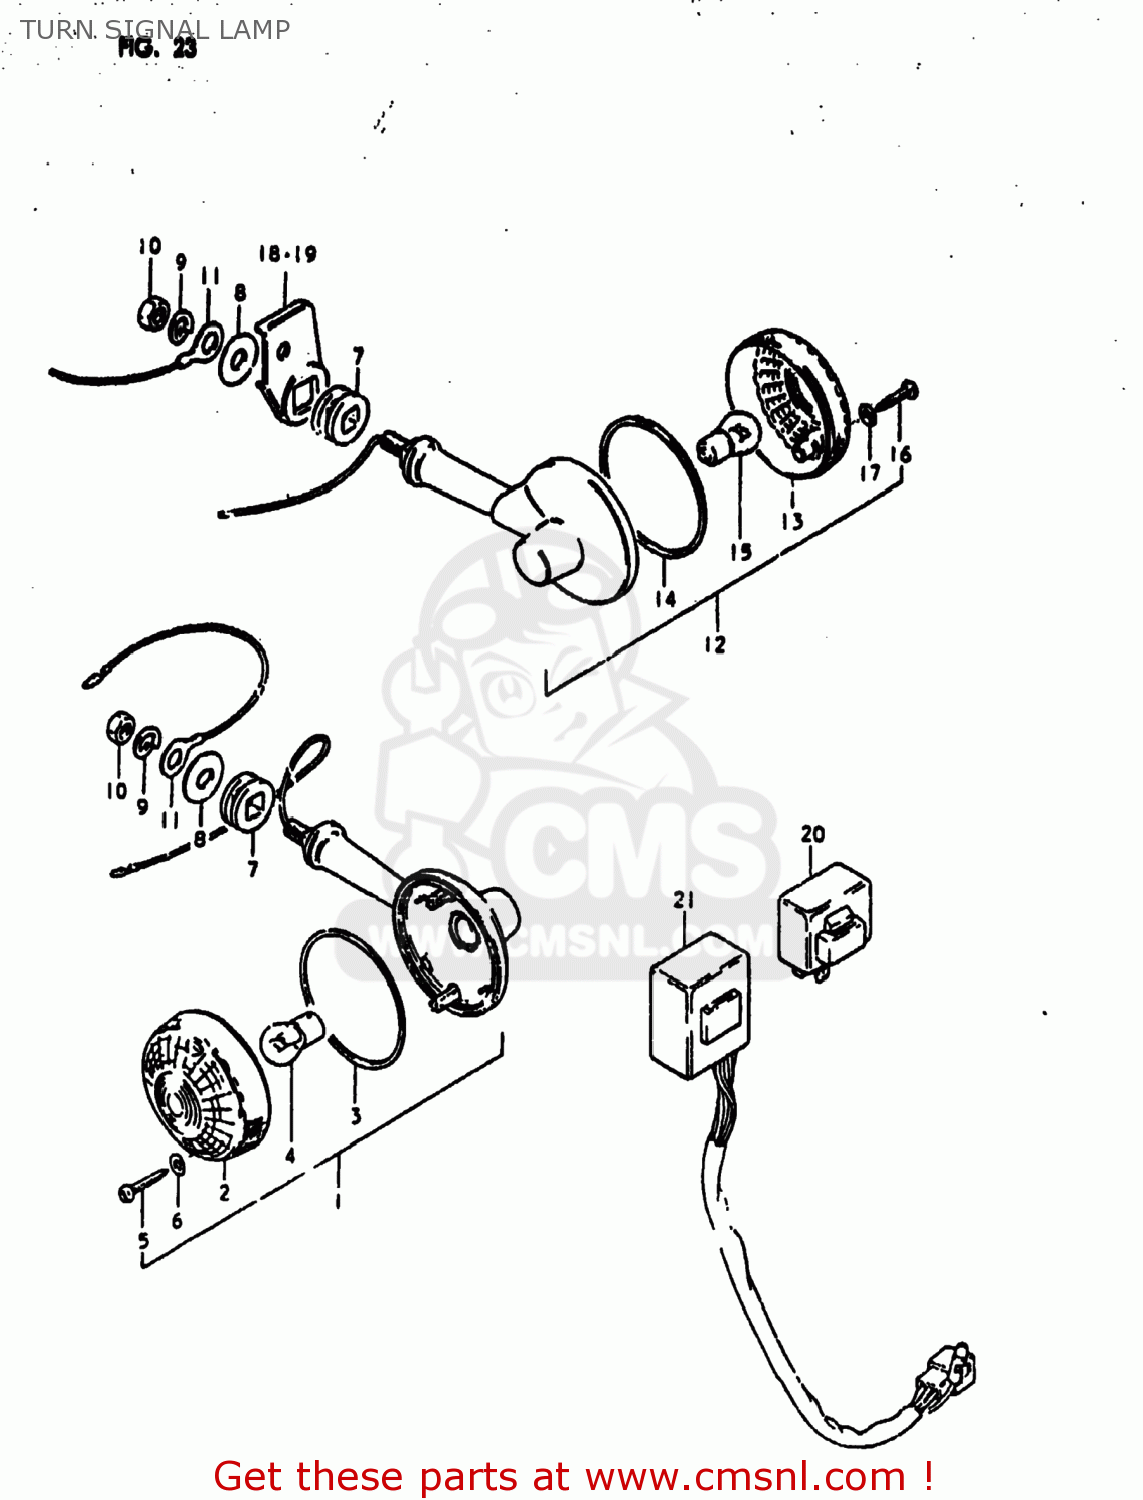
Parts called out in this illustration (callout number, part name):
1	LAMP ASSEMBLY,FRONT TURN SIGNAL
2	LENS
3	GASKET (NAS)
4	BULB(12V23W,STANLEY,A4577A)
5	BOLT
6	GASKET (NAS)
7	CUSHION
8	WASHER
9	LOCK WASHER
10	NUT
11	LEAD WIRE,EARTH
12	LAMP ASSEMBLY,FRONT TURN SIGNAL
13	LENS
14	GASKET (NAS)
15	BULB(12V23W,STANLEY,A4577A)
16	BOLT
17	GASKET (NAS)
18	BRACKET,RR TURNSIGNAL LAMP,R
19	BRACKET,RR TURNSIGNAL LAMP,L
20	UNIT,TURN SIGNAL CONTROL
21	RELAY,TURN SIGNAL
